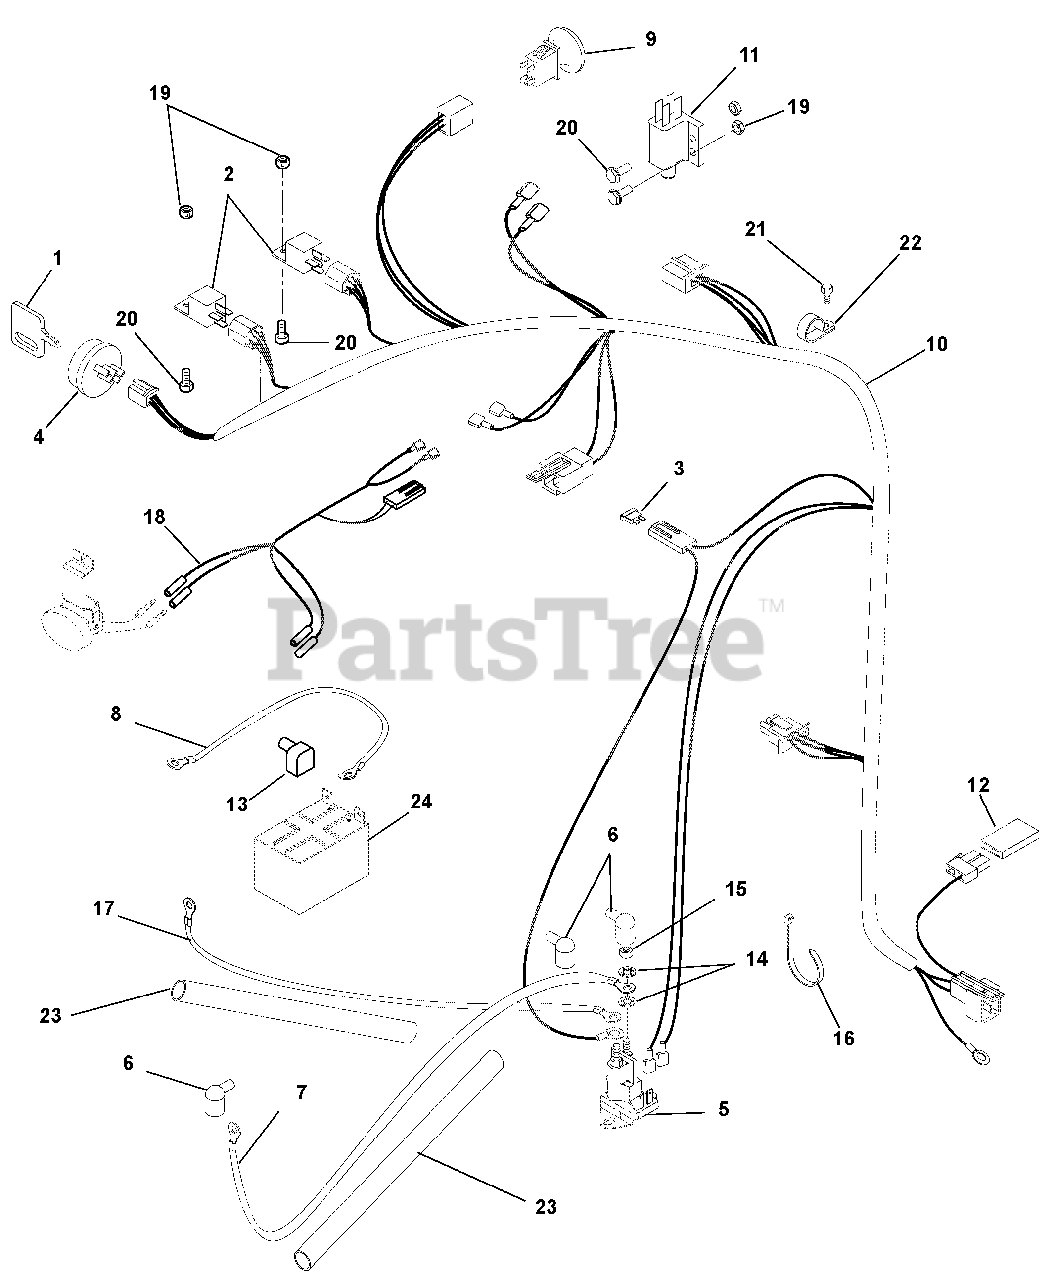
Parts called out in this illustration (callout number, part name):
1	Key with Cap
2	Relay
3	Fuse, 30 AMP
4	Key Switch
5	Solenoid
6	Boot, Eyelet Terminal
7	Starter Cable
8	Cable, Ground .25 x 13.00 x .31
9	Switch, Clutch With Retainer
10	Harness, ZTXL/ZoomXL
11	Switch, Double Pole N.O. / N.O.
12	Diode, Connector Shell
13	Insulator
14	Washer, Locking .31
15	Nut, Jam .31-24
16	Cable Tie
17	Starter Cable
18	Harness, Headlight
19	Nut, Locking Nylon With Insert 10-24
20	Screw, Hex Washer Head Machine 10-24 x .75
21	Screw, Tapping Hex Washer Head Thread Rolling .38-16 x .50
22	Clamp, Cushioned Steel .75
23	Sleeve, Anti-Abrasion
24	Battery, 12V, 215 CCA GEP
